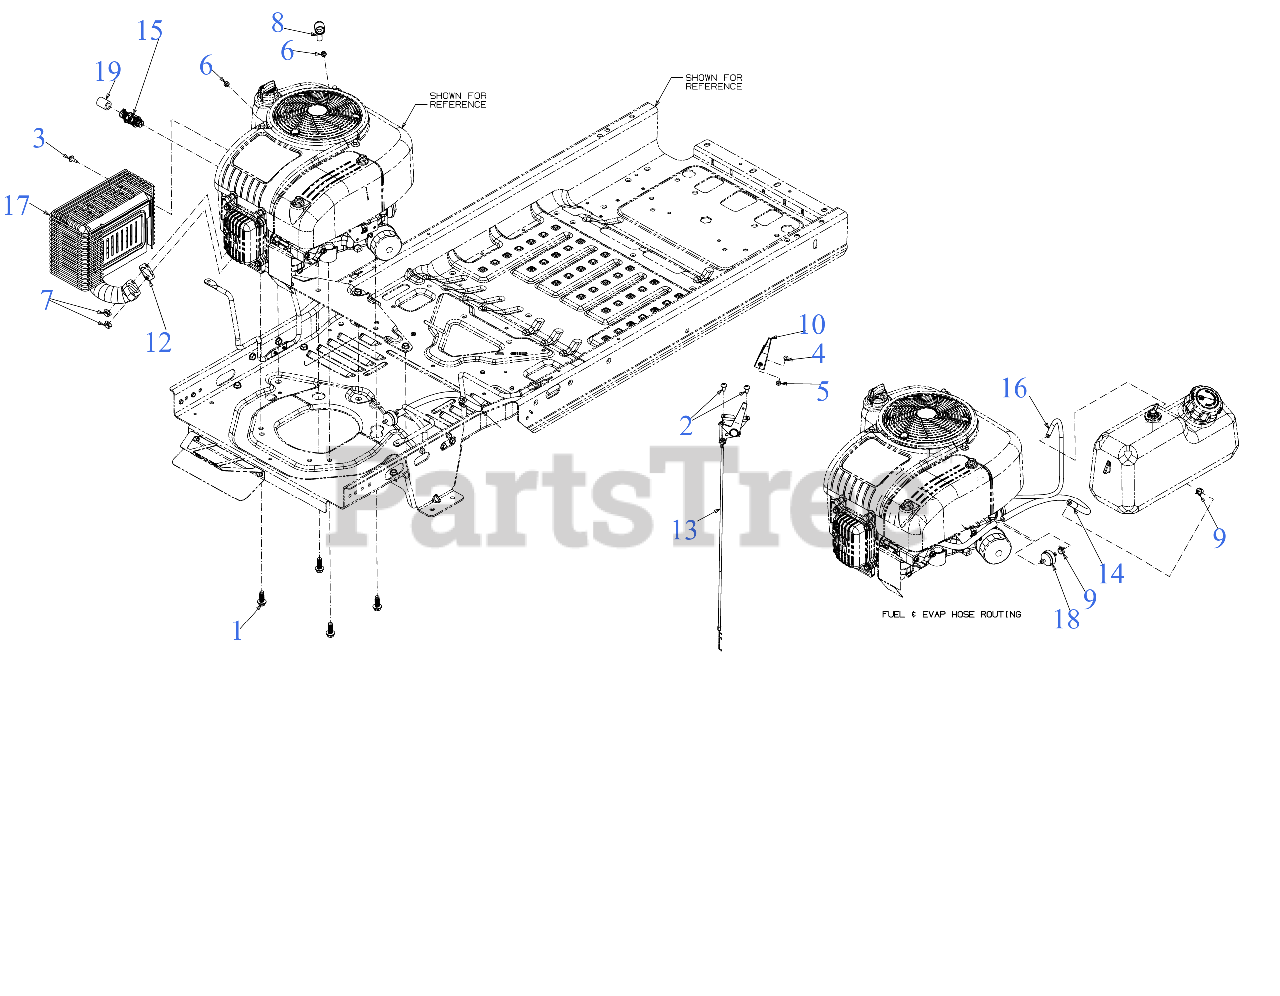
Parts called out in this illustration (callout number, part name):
1	SCREW 3/8-16 x 1
2	SCREW 1/4-20 x .5
3	SCREW M6-1 x .625
4	SCREW #8-32X.38 LG
5	HEX NUT 8-32
6	HEX NUT IK:M6
7	HEX FLANGE NUT M8X
8	TERMINAL COVER BLACK
9	HOSE CLAMP 1/20
10	THROTTLE CONTROL KNOB
12	EXHAUST PIPE MUFFLER GASKET
13	THROTTLE/CHOKE CABLE 19.0
14	FUEL HOSE LOW PERMEATION 13"
15	OIL DRAIN VALVE
16	VENT HOSE 3/16 ID 28"LG
17	MUFFLER ASSEMBLY
18	FUEL FILTER
18	Genuine Factory Parts FUEL FILTER
19	DRAIN HOSE 14''
